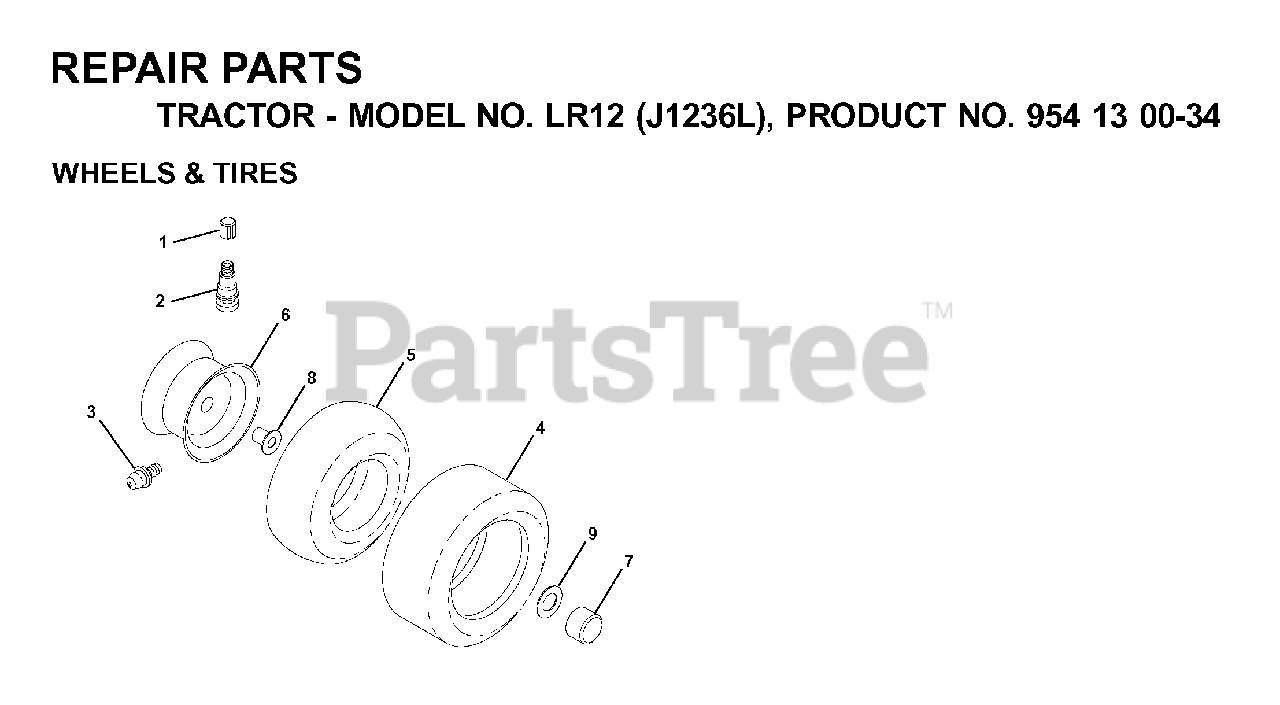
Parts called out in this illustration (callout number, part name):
1	VALVE CAP
2	VALVE STEM LT
3	FITTING LT
4	TIRE FRONT 15X6-6
4	REAR TIRE
5	TUBE.5.3/4.5/6
5	TUBE.16X6.5/7.5-8
6	RIM
6	RIM REAR 8"
7	CAP-HUB FRONT LT
8	BEARING T
